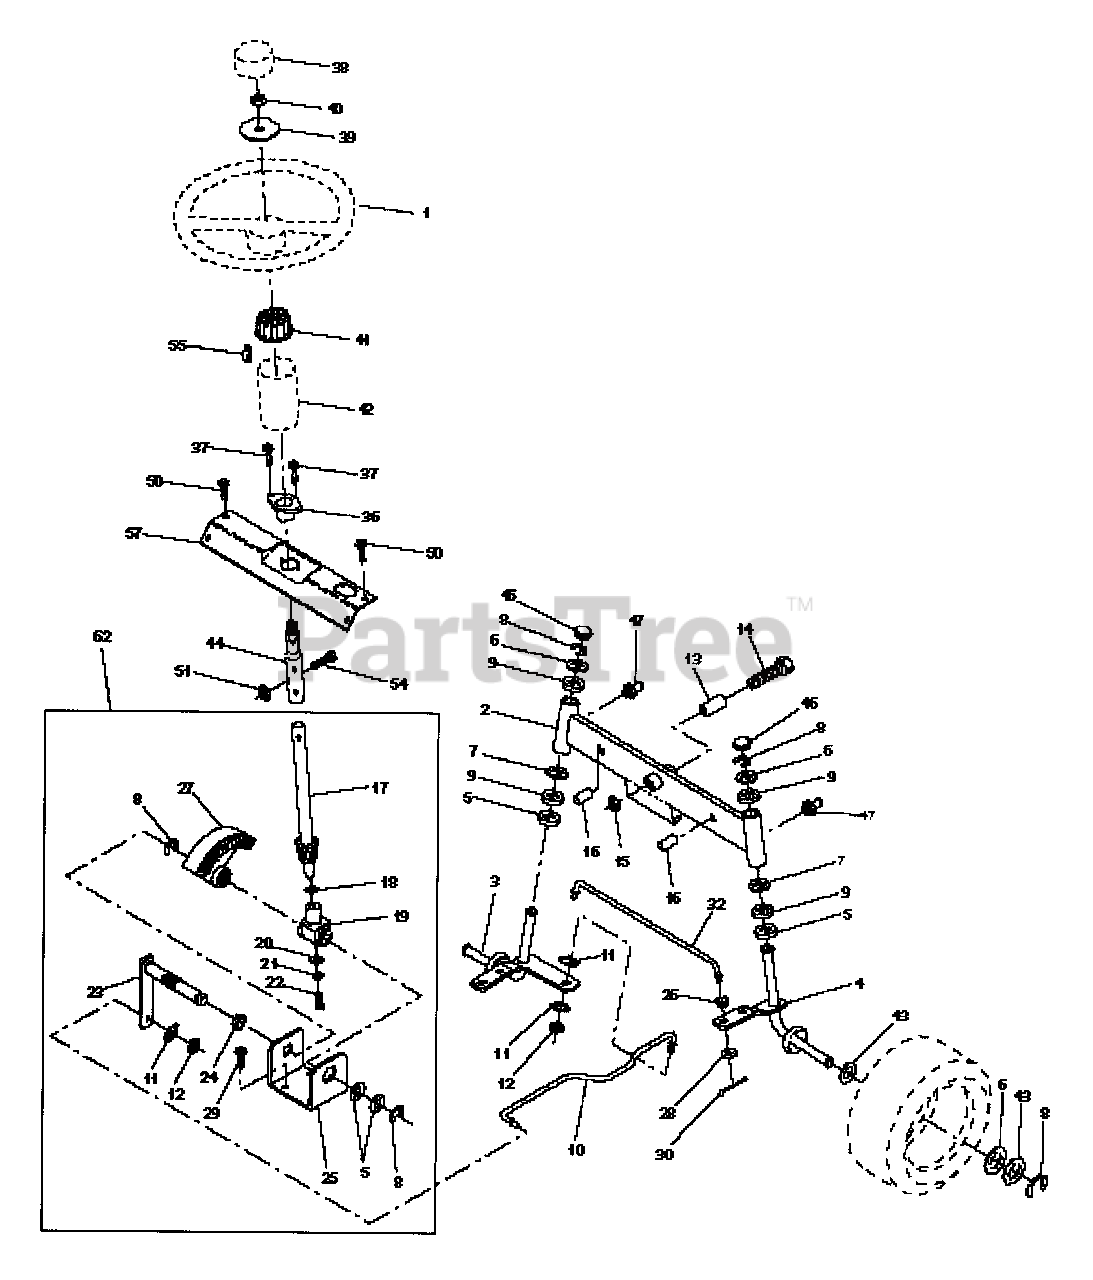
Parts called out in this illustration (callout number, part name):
1	Wheel Steering Auto Blk
2	Axle Asm Fr LT W/gzks 38/42
3	Spindle Asm LH
4	Spindle Asm RH
5	Bearing Race Thrust Harden
6	Washer 25/32 X 1-5/8 X 16 Ga
7	Washer 27/32 X 1-1/4 X 16 Ga
8	Ring Klip #t5304-75
9	Bearing Col Strg Blk
10	Link Drag Sol Ball Jt 20 064
11	Washer Lock Hvy Hlcl Spr 3/8
12	Nut Fin Hex 3/8-24 Unf
13	Spacer Bearing Axle Front
14	Bolt Hex 5/8-11 Unc X 3-1/2
15	Nut Lock Flange 5/8-11 Unc
16	Pin Axle 5/8 X 1 55/1 54 Lg
17	Shaft Asm Strg Private Label
18	Washer Thrust 515x 750x 033
19	Support Shaft
20	Washer Shim 1/4 X 5/8 X 062
21	Washer Lock Hvy Helical 1/4
22	Screw Hex Socket 1/4-20 X 5/8
23	Shaft Asm Pittman
24	Nyliner Snap In
25	Bracket Steering
26	Bushing Link Drag Blk LR
27	Gear Sector
28	Washer 13/32 X 7/8 X 16 Ga
29	Screw Thdrol 3/8-16x3/4 Ty-tt
30	Pin Cotter 1/8 X 3/4 Cad
32	Rod Tie Wire Form 19 75 Mech
36	Bushing Strg
37	Screw Slftp #10-16 X 1/2 Ty-b
38	Insert Cap Strg Wh Au
39	Washer 13/32 X 2-3/8 X 8 Ga
40	Nut Lock Center 3/8-24unf
41	Adaptor Wheel Strg 640/ 635id
42	Boot Steering Shaft
43	Washer 25/32 X 1 1/4 X 16 Ga
44	Shaft Extention Steering
46	Cap Spindle Fr Top Blk
47	Fitting Grease
50	Screw Hex Wsh Thdrol 1/4-20 x 3/4
51	Nut Lock Hex w/Ins 5/16-18
54	Bolt Fin Hex 5/16-18 Unc x 1-1/4
55	Clip Tinnerman
57	Support Shaft Steering
62	Kit, Steering Assembly, Service
